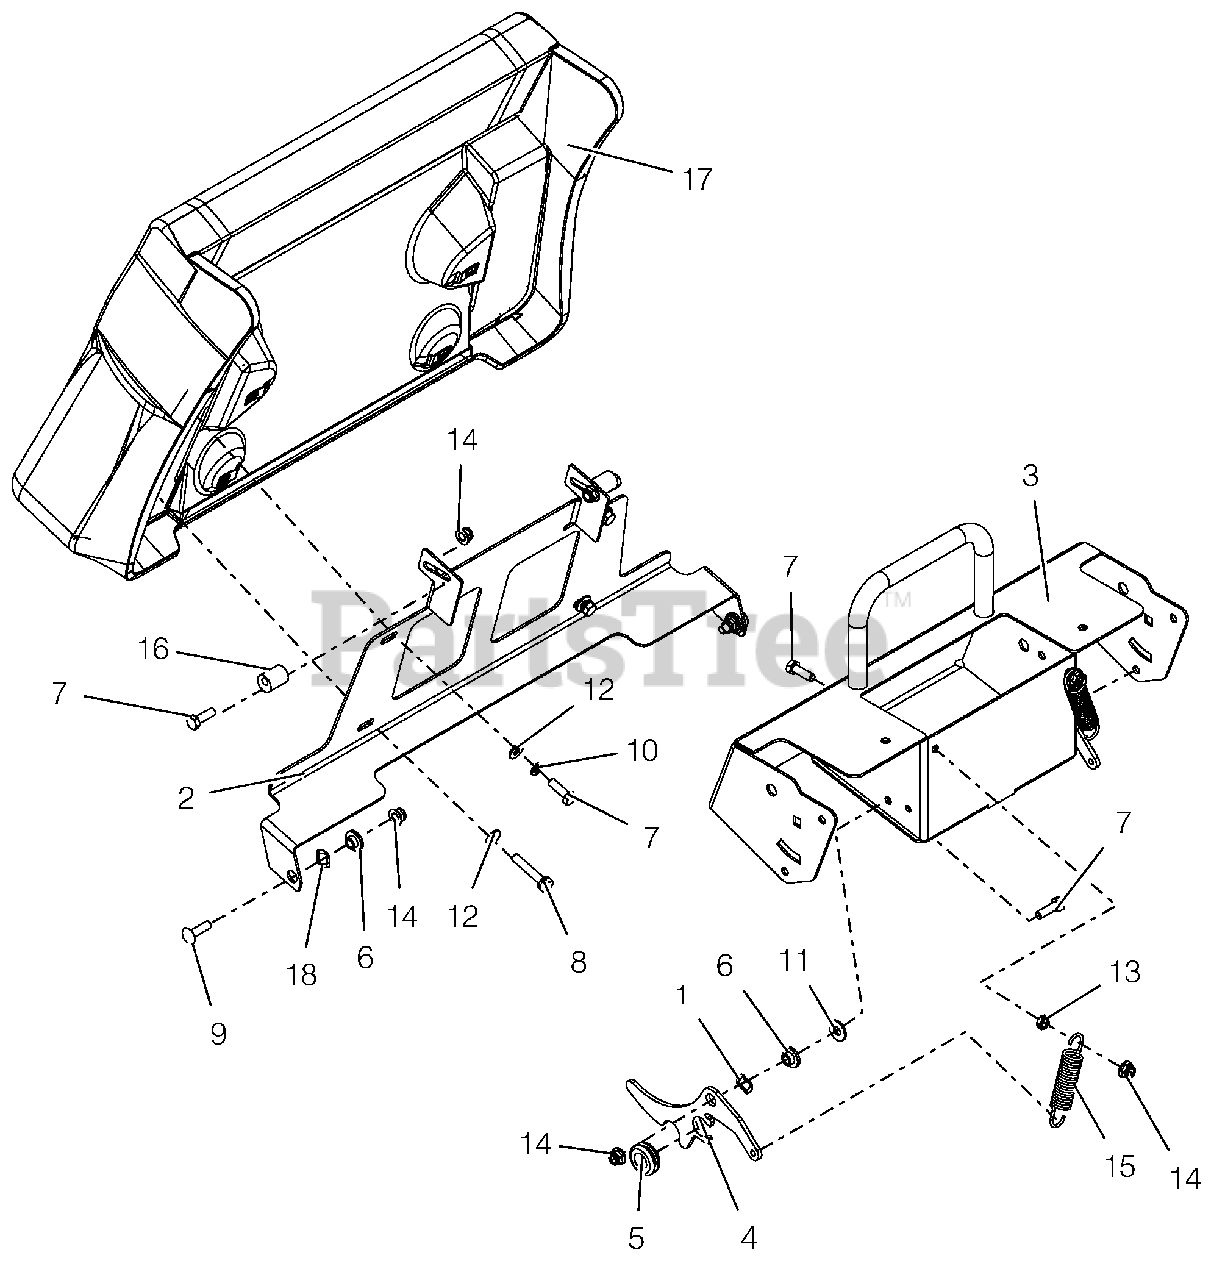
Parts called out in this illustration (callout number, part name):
1	WAVE WASHER .531X.781X.125FH
2	PAD, MOUNT
3	WLDMT, CONTROL PANEL PROSTANCE
4	LATCH, PAD MOUNT
5	GROMMET, SPLIT RUBBER
6	BSHG-FLG .32X.500X.344X.880
7	@BLT-HEX .31-18X1.00 GR5 YWZC
8	@BLT-HEX .31-18X1.75 GR5 YWZC
9	BLT-RDHDSQSHNK.31-18X1.13 G5YZ
10	@WSHR-LK .31X.078 REG YWZC
11	@WSHR-FL-STL.38X.875X.083 YWZC
12	@WSHR-FL-STL.312X.734X.065 YWZ
13	@NUT-LK-CTR-JAM .31-18 YWZC
14	@NUT-LK-NYL-FLG .31-18 YWZC
15	SG-TENS .105X.812X3.88 WLD 15
16	ECCENTRIC
17	PAD, PRO-STANCE OPERATOR
18	WAVE WASHER .531X.781X.125FH
